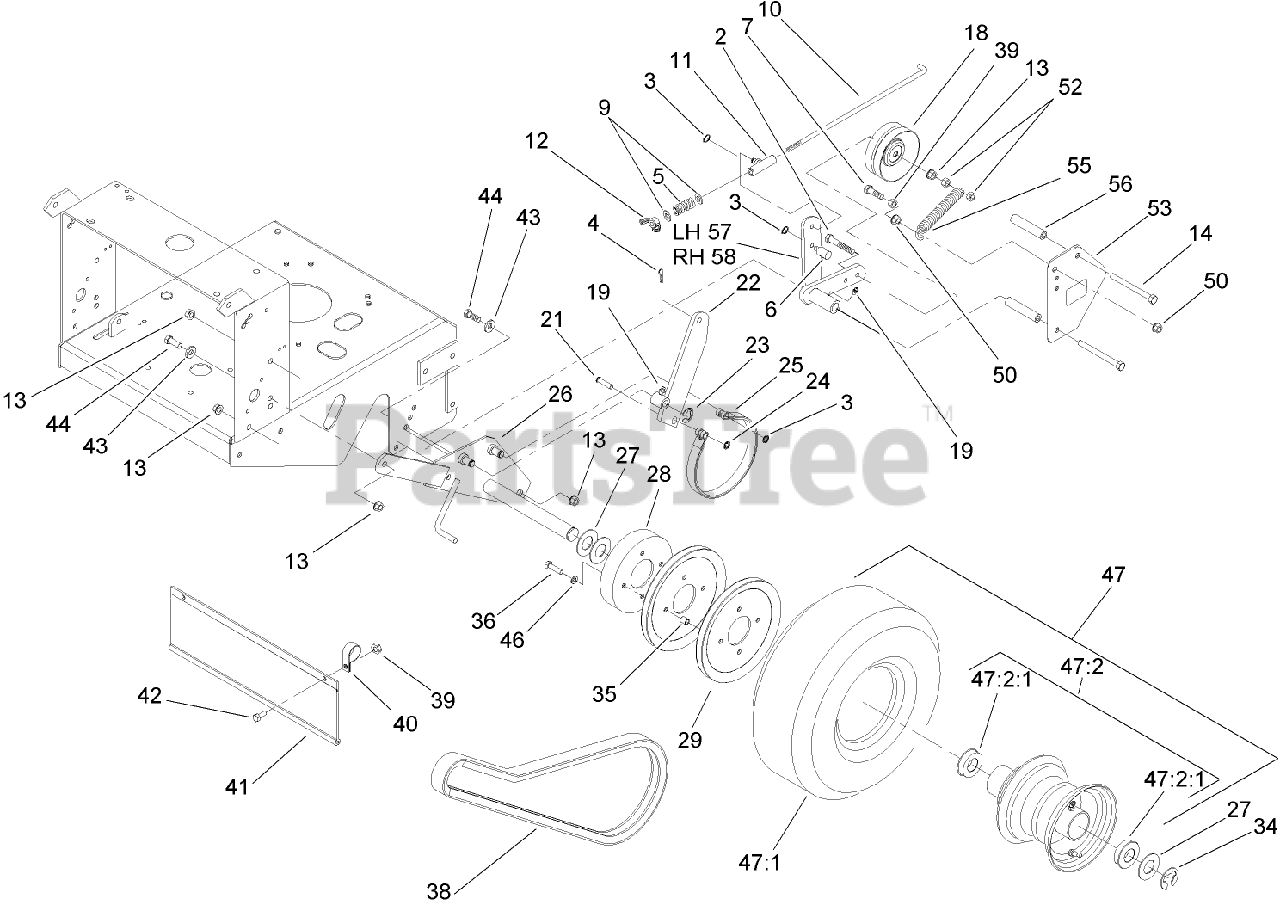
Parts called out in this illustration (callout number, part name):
2	SCREW-HH
3	RING-RETAINING
4	PIN-COTTER
5	SPRING-COMPRESSION
6	Swivel-Lever, Drive
7	SCREW-HH
9	WASHER-PLAIN
10	Linkage-Brake
11	SWIVEL-BRAKE
12	WINGNUT-NYLOCK
13	NUT-HHF, WHIZ
14	SCREW-HH
18	IDLER-WHEEL, DRIVE
19	FITTING-GREASE
21	PIN-CLEVIS
22	ARM-BRAKE
23	RING-RETAINING, EXTERNAL
24	NUT-PUSH
25	BAND-BRAKE
27	WASHER-SPACER
28	DRUM-BRAKE
29	SHEAVE-WHEEL, DRIVE
34	RING-SNAP
35	SPACER-SHEAVE, WHEEL
36	SCREW-HH
38	V-BELT
39	NUT-LOCK, NI
40	CLAMP-R
41	SHIELD-TRAILING
42	SCREW-HH
43	WASHER-BELLEVILLE
44	SCREW-HH
46	WASHER-LOCK
47	WHEEL AND TIRE ASM
47:1	Tire-Turfmaster
47:2	WHEEL AND HUB ASM
47:2:1	BEARING-FLANGED
50	NUT-HF
52	NUT-LOCK, NI
53	Shield-Wheel, Drive
55	SPRING-EXTENSION
56	SPACER-SHIELD
57	Arm-Idler, LH
58	Arm-Idler, RH
